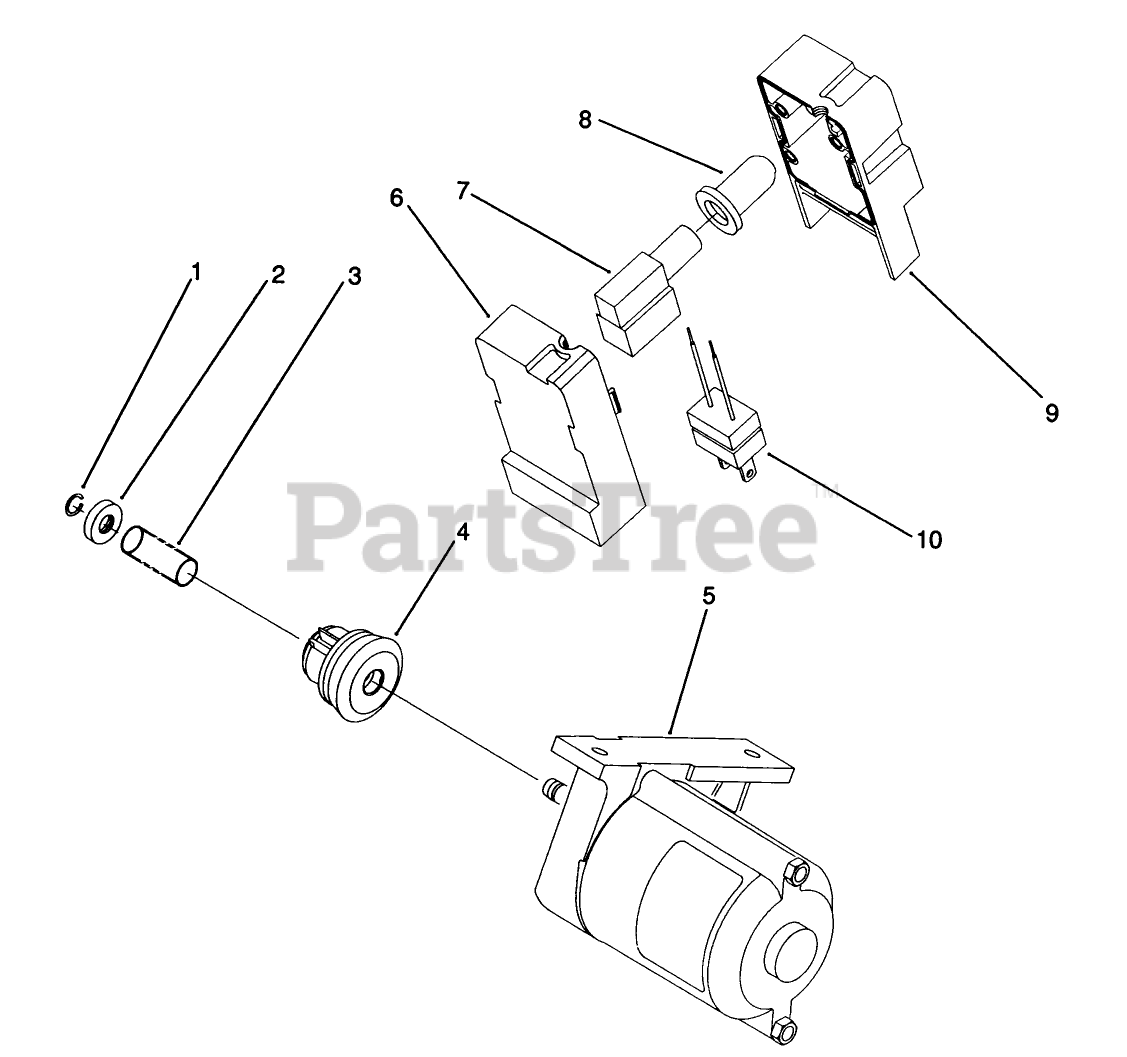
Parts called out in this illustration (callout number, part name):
1	RING-LOCK
2	PINION STOP
3	SPRING
4	ORDER BRIGGS 801293
7	SWITCH-STARTER
8	BOOT-SWITCH
